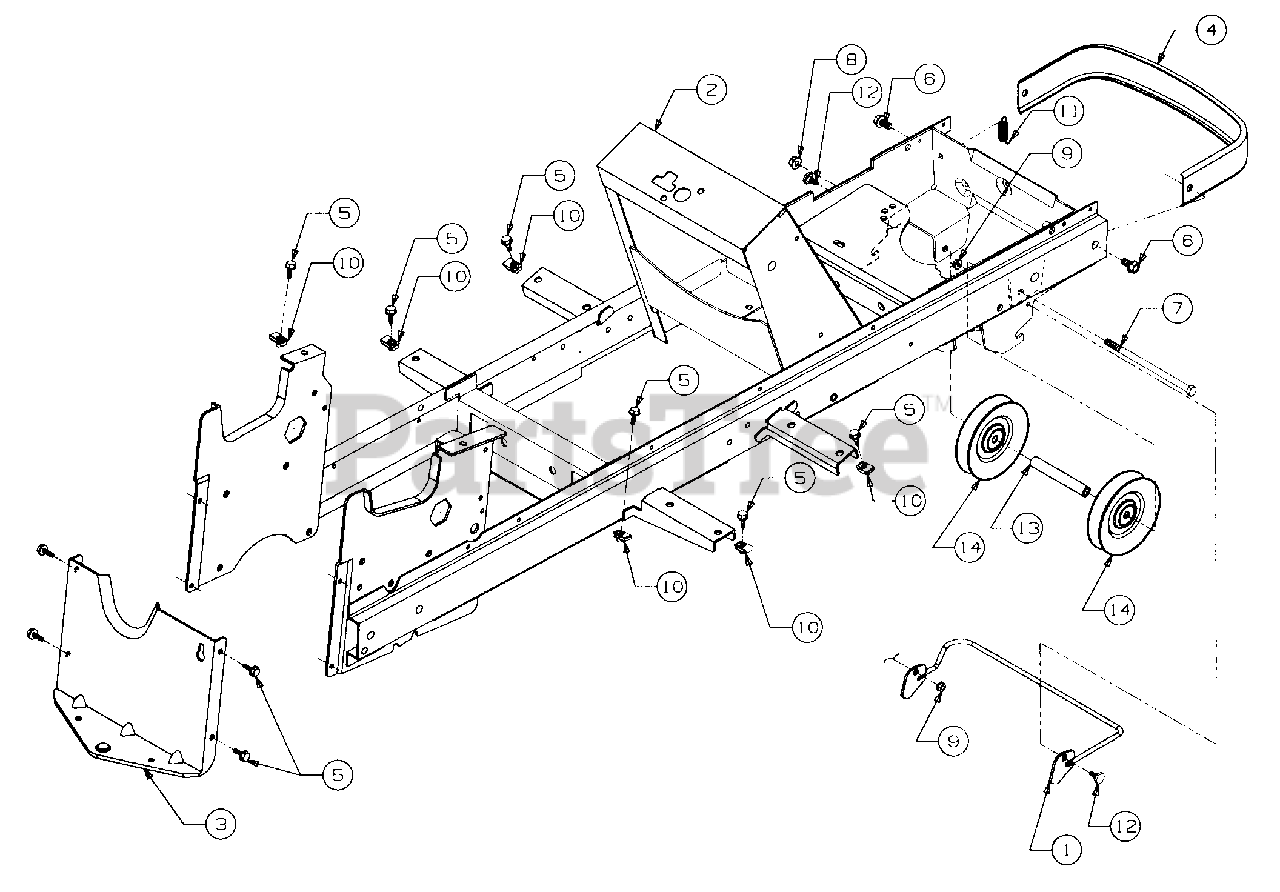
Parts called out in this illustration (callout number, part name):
6	Screw, Hex Wash 3/8-16 x .75 Lg Tapp
7	Screw, Hex Cap, 3/8-16 x 7.0 Lg
8	Nut, Hex Flanged Lock, 3/8-16
9	Nut, Hex Flange Lock, 1/4-20
10	U-Nut, 5/16-18
11	Spring, Latch
12	Bolt, Shoulder
13	Spacer, Idler, .407 ID x .62 OD x 4.38 Lg
14	Pulley, Idler
